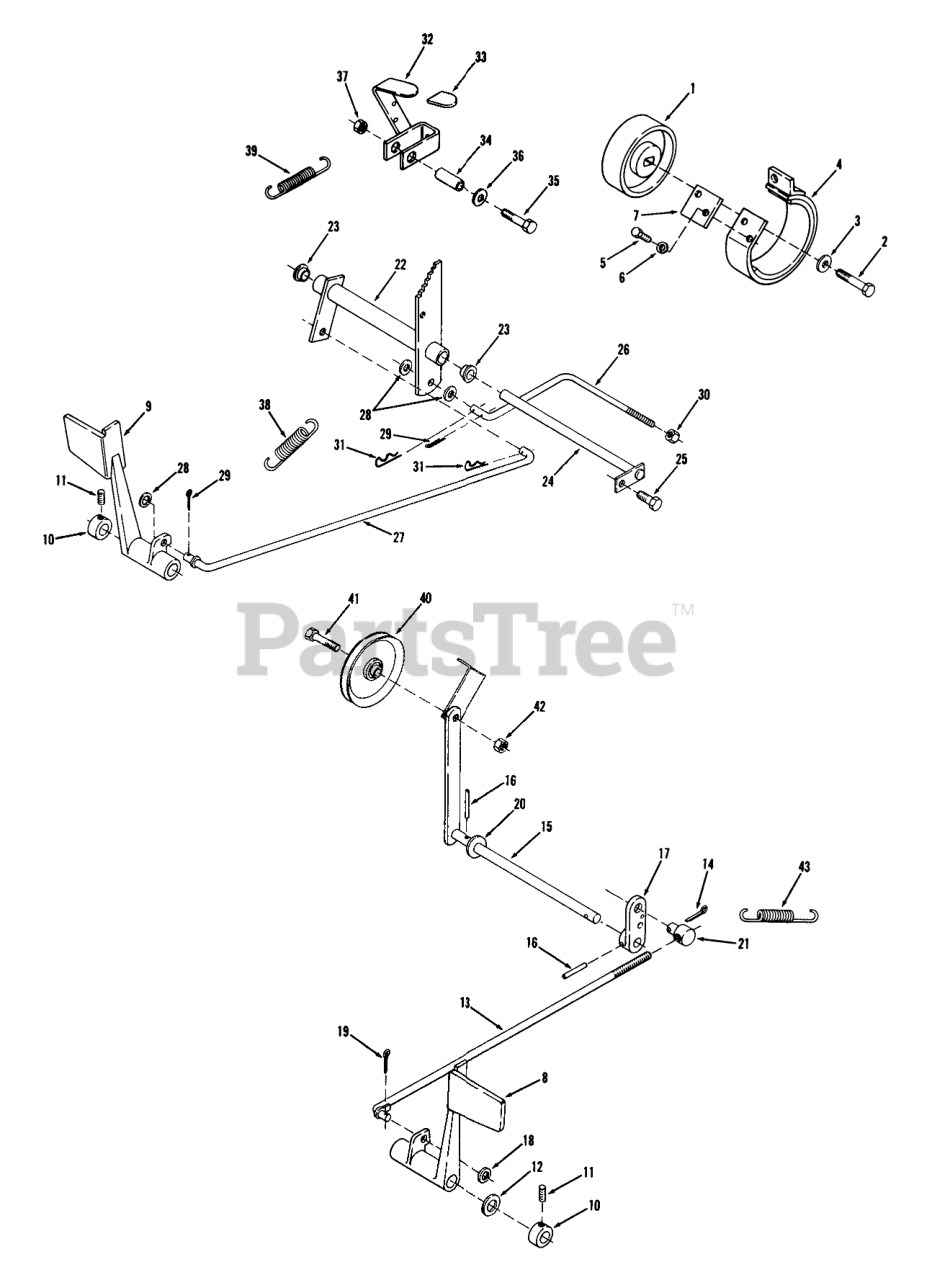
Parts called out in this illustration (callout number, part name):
1	Brake Drum
2	Bolt
3	WASHER
4	BRAKE BAND ASM
5	H H C S
6	Washer
7	Plate-Stop
8	Clutch Pedal
9	PEDAL-BRAKE R
10	Collar
11	SCREW-SET
12	WASHER-BOWED
13	ROD AND GUIDE ASM
15	Idler Arm Assy
16	PIN-SPIROL
17	Arm-Clutch Rod
18	WASHER-NYLON
19	Pop Rivet
20	SHIM-WASHER
21	TRUNNION
22	Bellcrank Assy
23	BUSHING-FLANGED
24	Rod Assy
25	SCREW
26	Brake Rod
28	WASHER-NYLON
29	Pop Rivet
30	NUT
31	Hairpin
32	Brake Lever Assy
33	GRIP
34	SPACER
35	Bolt
36	Washer
37	LOCKNUT-FLANGE
38	Spring
39	SPRING-EXTENSION
40	PULLEY-IDLER
41	HEX HD CAP SCREW
42	Nut
43	Spring
